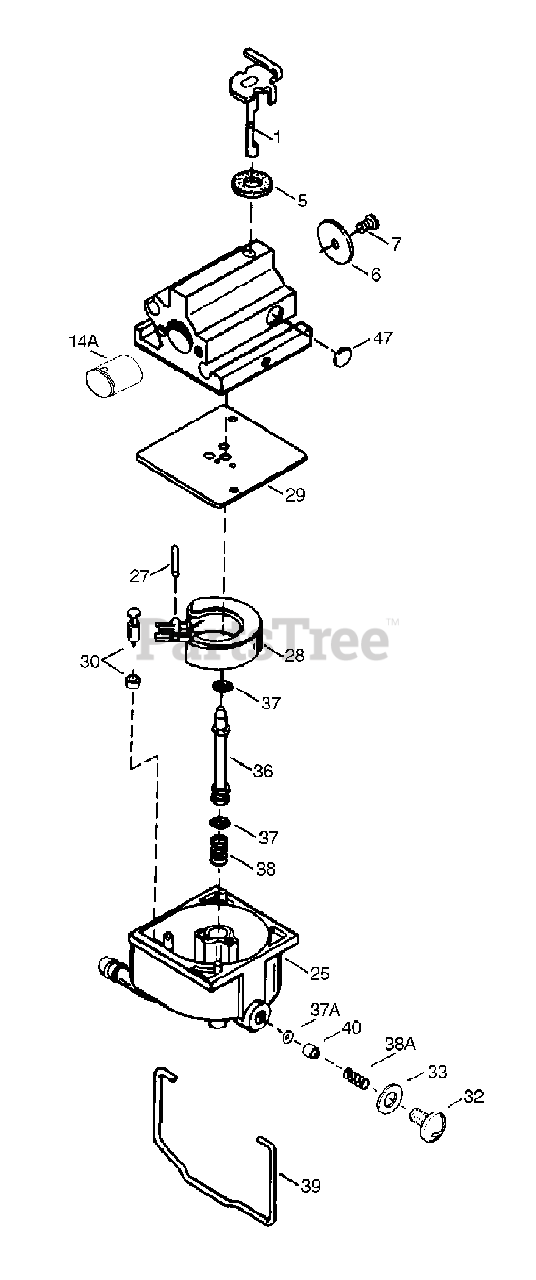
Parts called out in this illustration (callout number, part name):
1	Throttle Shaft & Lever Assembly
5	Dust Seal
6	Throttle Shutter
7	Throttle Shutter Screw
14A	Venturi
25	Float Bowl
27	Float Shaft
29	Float Bowl to Body Gasket
30	Inlet Needle & Seat
32	Bowl Drain Screw
33	Bowl Drain Washer
36	Main Nozzle Tube
37	"O" Ring
38	Main Nozzle Tube Spring
39	Float Bowl Retainer
40	Main Fuel Jet
47	Idle Mixture Well Welch Plug
